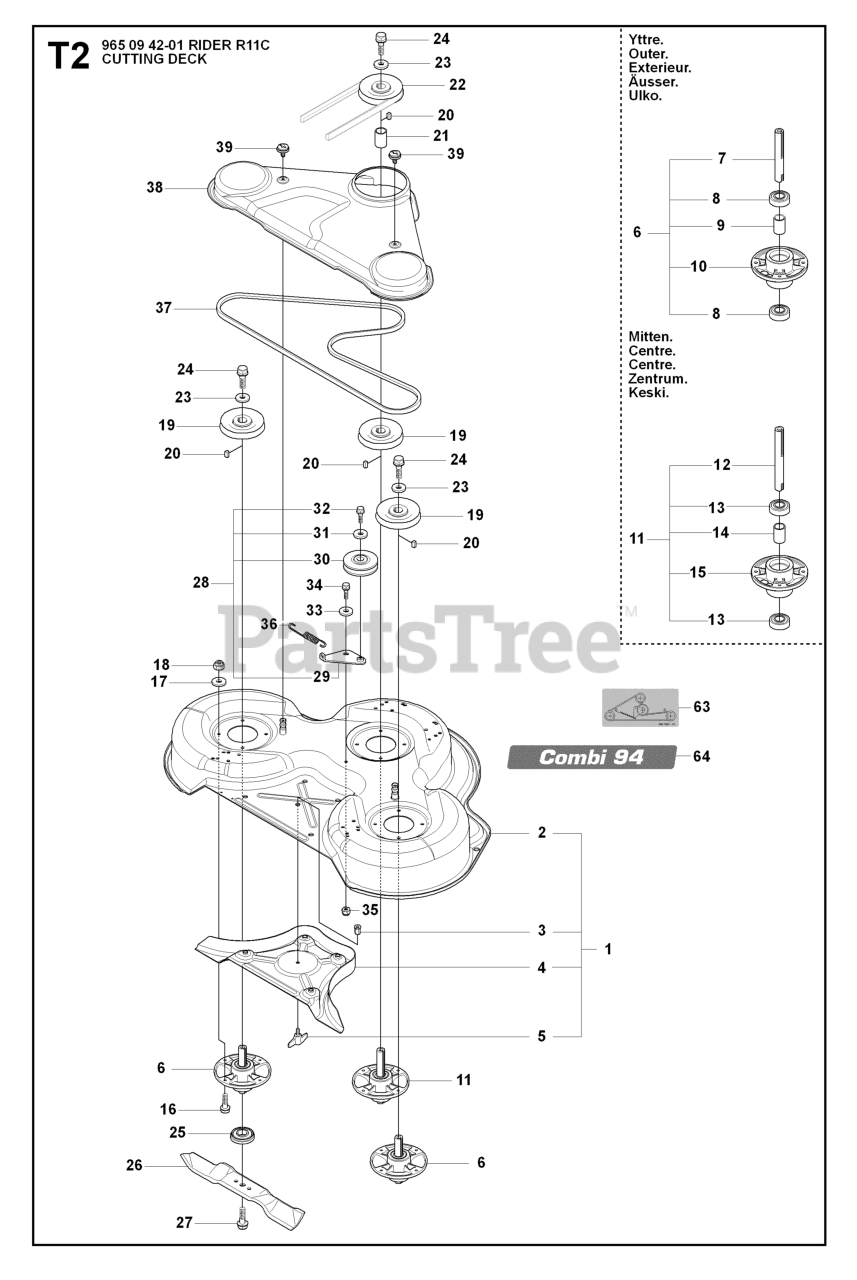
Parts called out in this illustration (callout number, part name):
4	PLUG C93 & C94
6	RP SPINDLE ASSY
10	BEARING HOUSING
15	BEARING HOUSING
17	WASHER BRB 8.4X17
18	LOCKNUT M8
21	SPACING SLEEVE
25	BLADE BRACKET
30	PULLEY
33	WASHER
35	LOCKNUT M8
37	BELT A69
38	BELT COVER C93 & C94 GREY
